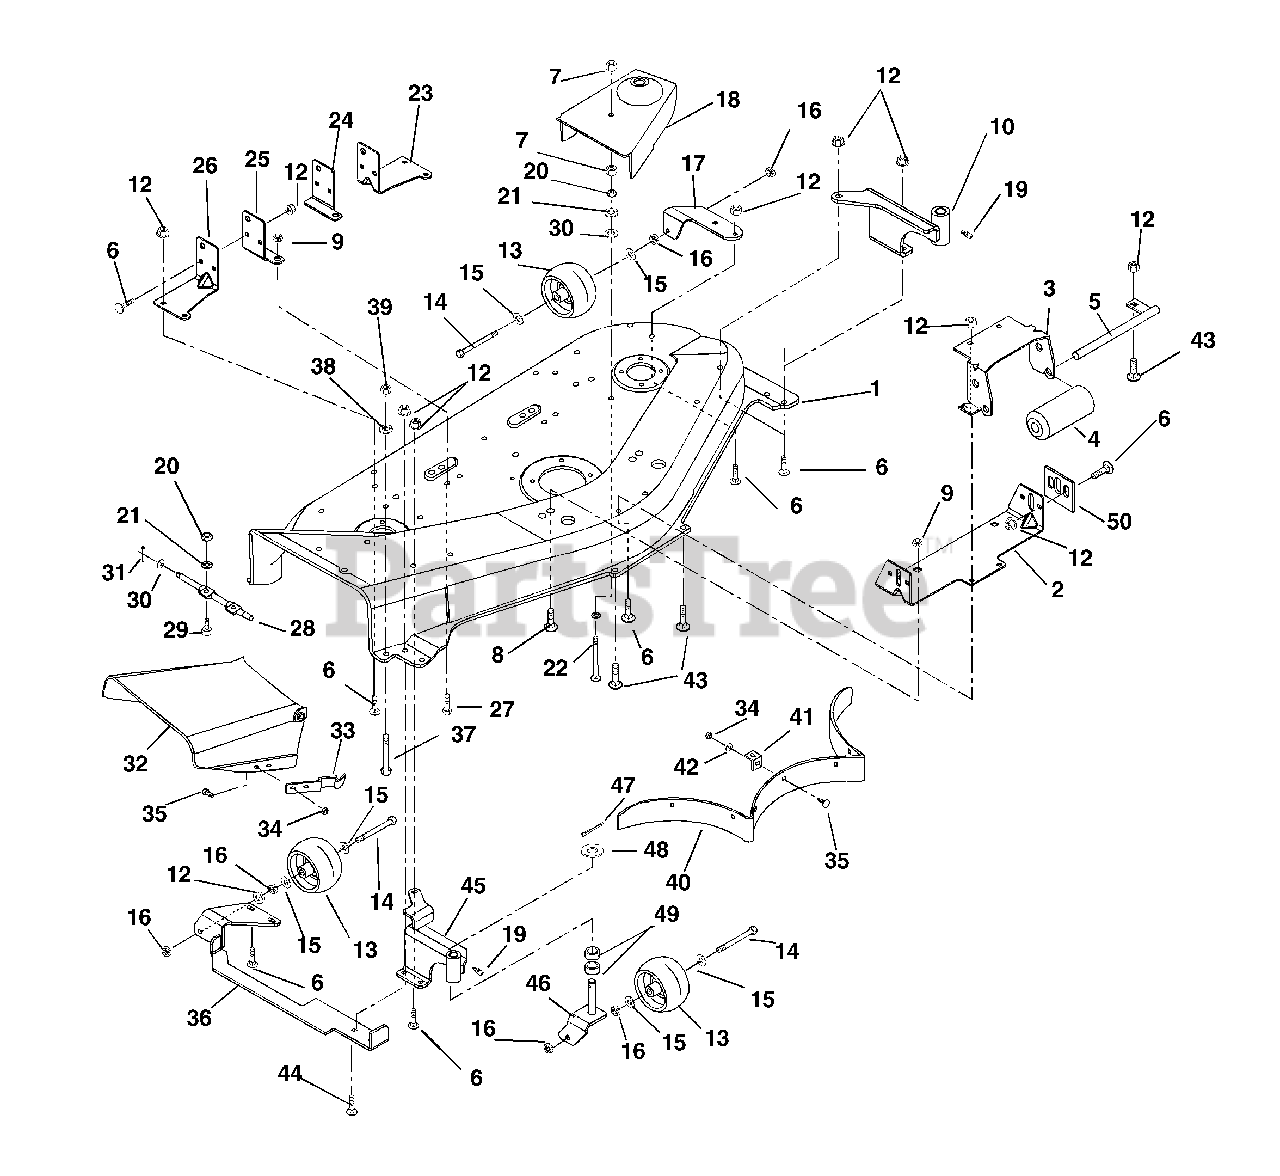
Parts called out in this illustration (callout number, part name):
1	MOWER PAN W/DECALS 48"- ORANGE
2	FRONT HANGER
3	BRACKET, ROLLER
5	ROLLER SHAFT
6	@BLT-RDHDSQNK .31-18X.75 G5YZ
7	@NUT-LK-CTR .31-18 YWZC
8	@BLT-RDHDSQNK .50-13X1.00 G5YZ
9	@NUT-LK-CTR .50-13 YWZC
10	WELDMENT-LEFT FRONT
11	BLT-RDHDSQSHK.31-18X.75 GR2 YW
12	@NUT-LK-TOP-FLG .31-18 YWZC
14	@BLT-HEX .38-16X3.50 GR5 YWZC
15	@WSHR-FL-STL.38X.875X.083 YWZC
16	@NUT-LK-CTR .38-16 YWZC
17	BRACKET-LEFT REAR
18	R.H. BELT COVER
18	COVER, LEFT HAND
19	FTG-LUBE .25-28X.256 YWZC
20	@NUT-HEX .31-18 YWZC
21	@WSHR-LK .31X.078 REG YWZC
22	BLT-RDHDSQNK .312-18X3.25 YWZC
23	LH REAR HANGER
24	LEFT HAND REAR HANGER SUPPORT
25	RH REAR HANGER SUPPORT
26	RH REAR HANGER
27	@BLT-HEX .50-13X1.00 GR5 YWZC
28	HINGE PIN
29	@BLT-HEX .31-18X.75 GR5 YWZC
30	@WSHR-FL-STL.406X.812X.065 YWZ
31	@PIN-CTR .09X.75 EXTPRSQCT YWZ
32	CHUTE EXTENSION
33	FLAT SPRING - ORANGE
34	@NUT-LK-CTR .25-20 YWZC
35	@BLT-RDHDSQNK .25-20X.50 G5YZ
36	WELDMENT-RIGHT REAR
37	@BLT-RDHDSQNK .38-16X2.50 G5YZ
38	WSHR-LK .375X.115 HVY YWZC
39	@NUT-HEX .38-16 YWZC
40	BAFFLE
41	BAFFLE TAB
42	@WSHR-FL-STL.281X.62X.065 YWZC
43	@BLT-RDHDSQNK .31-18X1.50 G5YZ
44	@BLT-RDHDSQNK .31-18X1.00 G5YZ
45	WELDMENT-RIGHT FRONT
46	WELDMENT-CASTER FORK
47	@PIN-CTR .18X1.25 EXTPRSQCT YZ
48	WSHR-FL-STL .630X1.005X.062 YZ
49	BSHG-SLV .625X.750X.500 BR
50	MOWER ADJUSTMENT TAB
